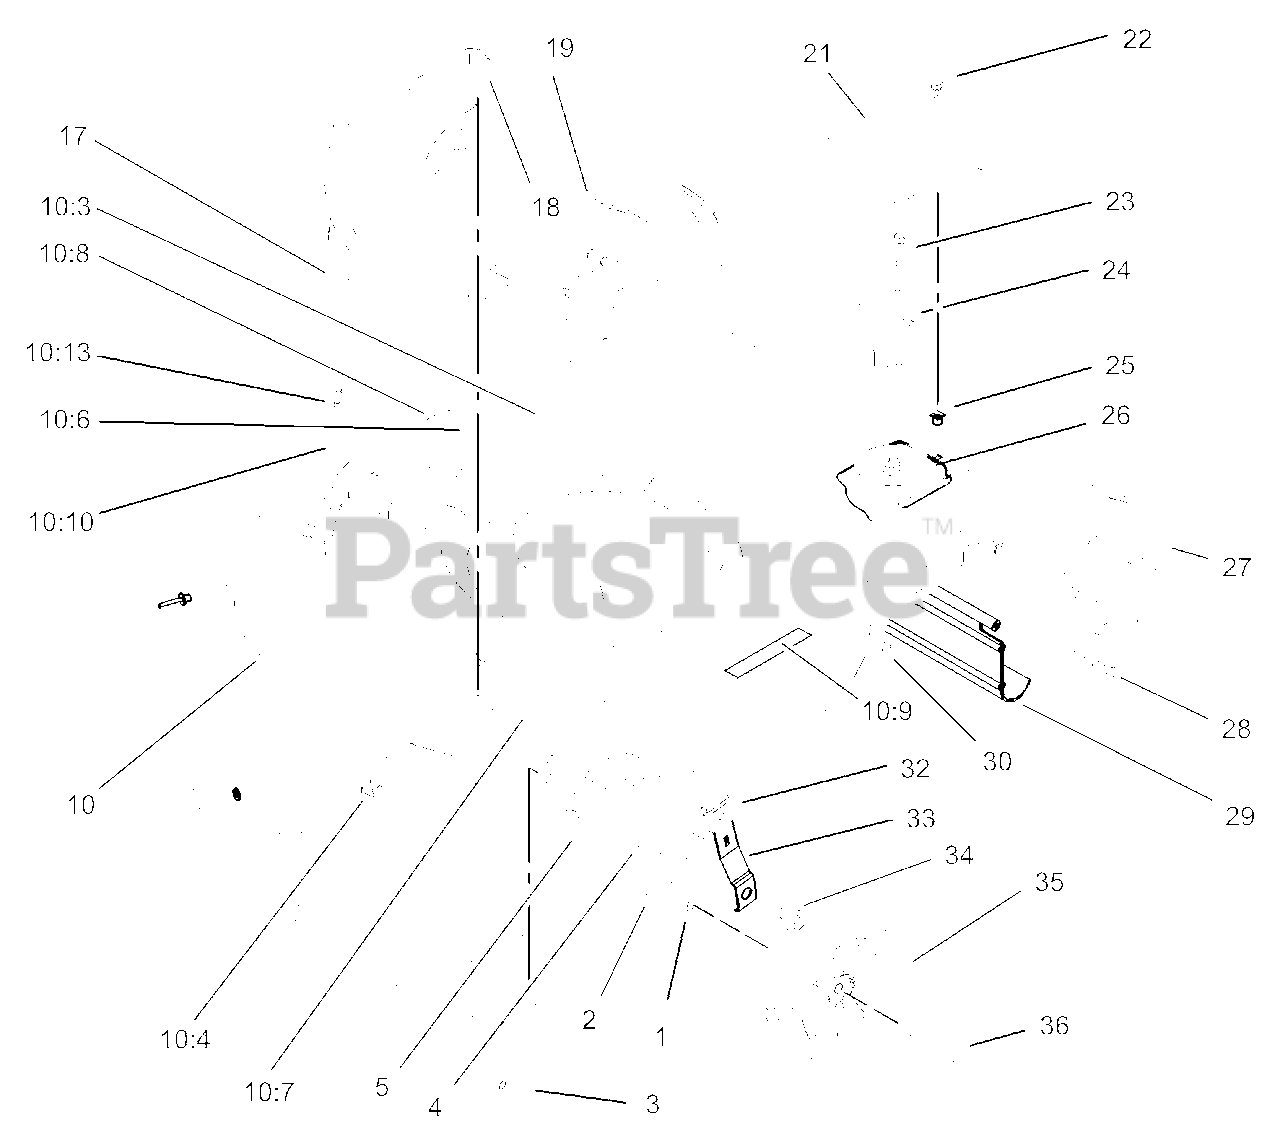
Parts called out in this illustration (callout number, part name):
2	Bracket-Height Adjustment, Wheel
3	Plate-Baffle
4	Washer-Wheel
5	Plate-Height, Adjustment
10	Deck ASM
10:3	Decal-Danger
10:4	Nut-Cage
10:6	Decal-Warning
10:7	Decal-HOC, LH
10:8	Decal-HOC, RH
10:9	Decal-Warning
10:10	Grommet-Plastic
10:13	Screw-Sems
17	Plate-Mulch
19	RH Bracket ASM
21	Cover-Drive
23	Screw-HWHTF
24	Guide-Transmission
25	Grommet
26	Gear Case ASM
27	LH Bracket ASM
28	Screw-HH
29	Shield-Trailing
30	Nut-Lock, NI
32	Knob-Lever, Height Adjustment
33	Arm-Front Spring
34	Bolt-Shoulder
35	Bolt-Shoulder
36	Wheel & Tire ASM
